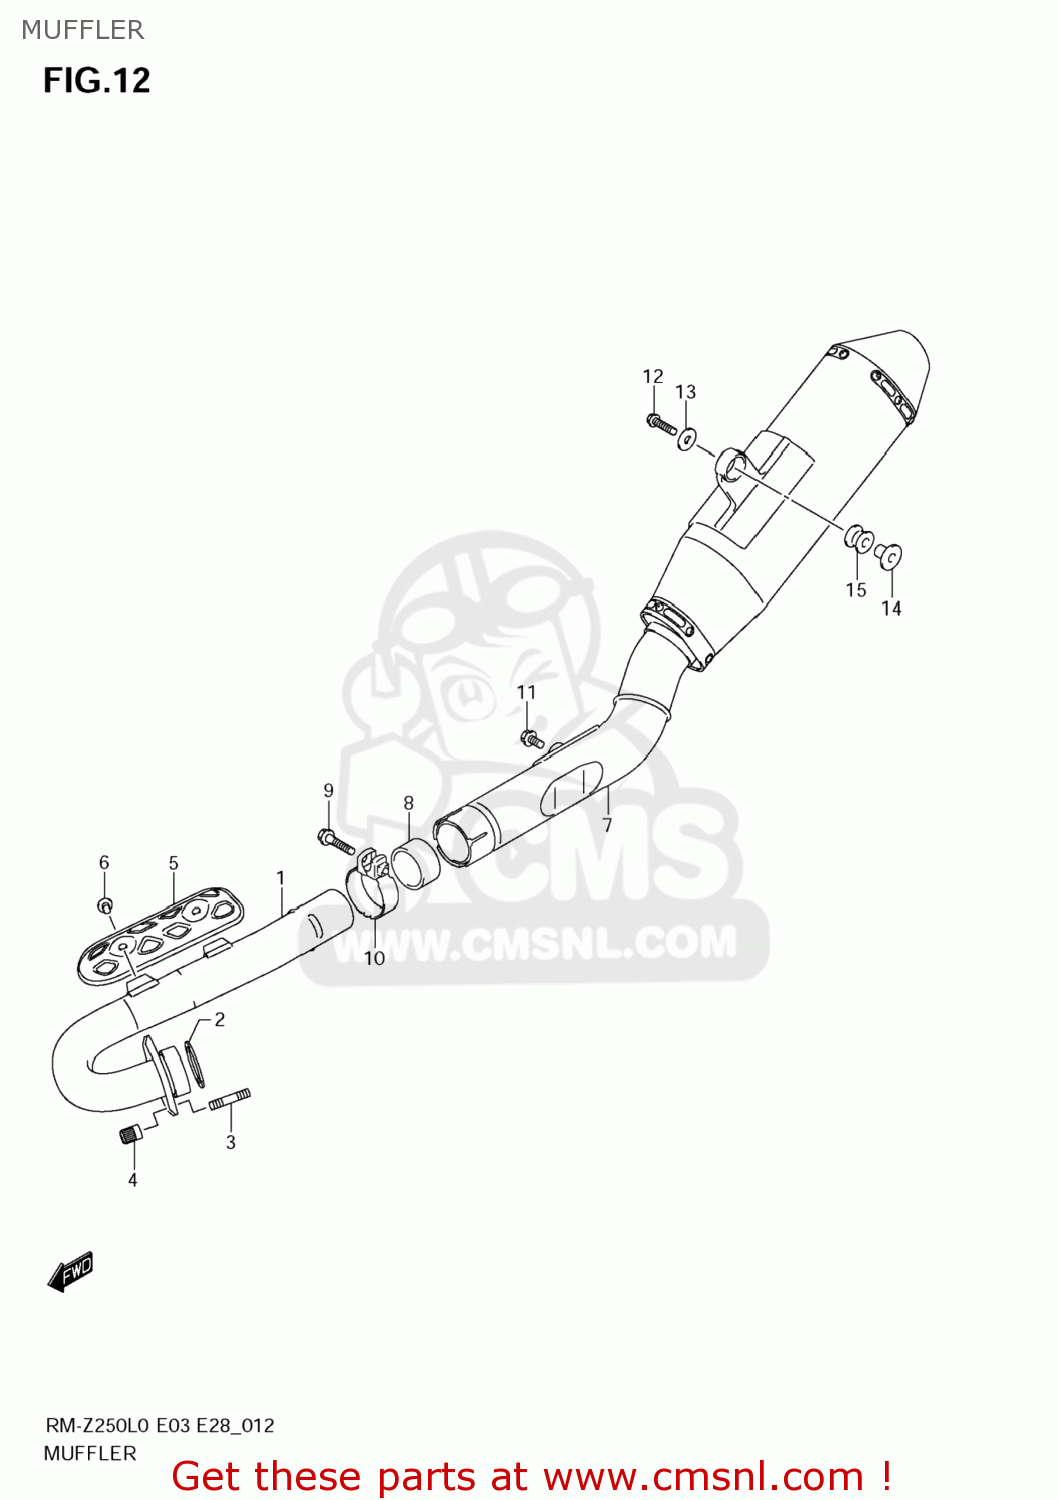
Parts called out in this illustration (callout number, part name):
1	PIPE,EXHAUST
2	GASKET,EXHAUST PIPE (NAS)
3	BOLT,STUD
4	NUT
5	COVER,EXHAUST PIPE
6	BOLT(6X8)
7	BODY,MUFFLER
8	CONNECTOR,MUFFLER
9	BOLT
10	CLAMP,CONNECTOR
11	BOLT(8X20)
12	BOLT(8X35)
13	WASHER(8.5X26X1.6)
14	SPACER(8.6X12X18.5)
15	CUSHION
